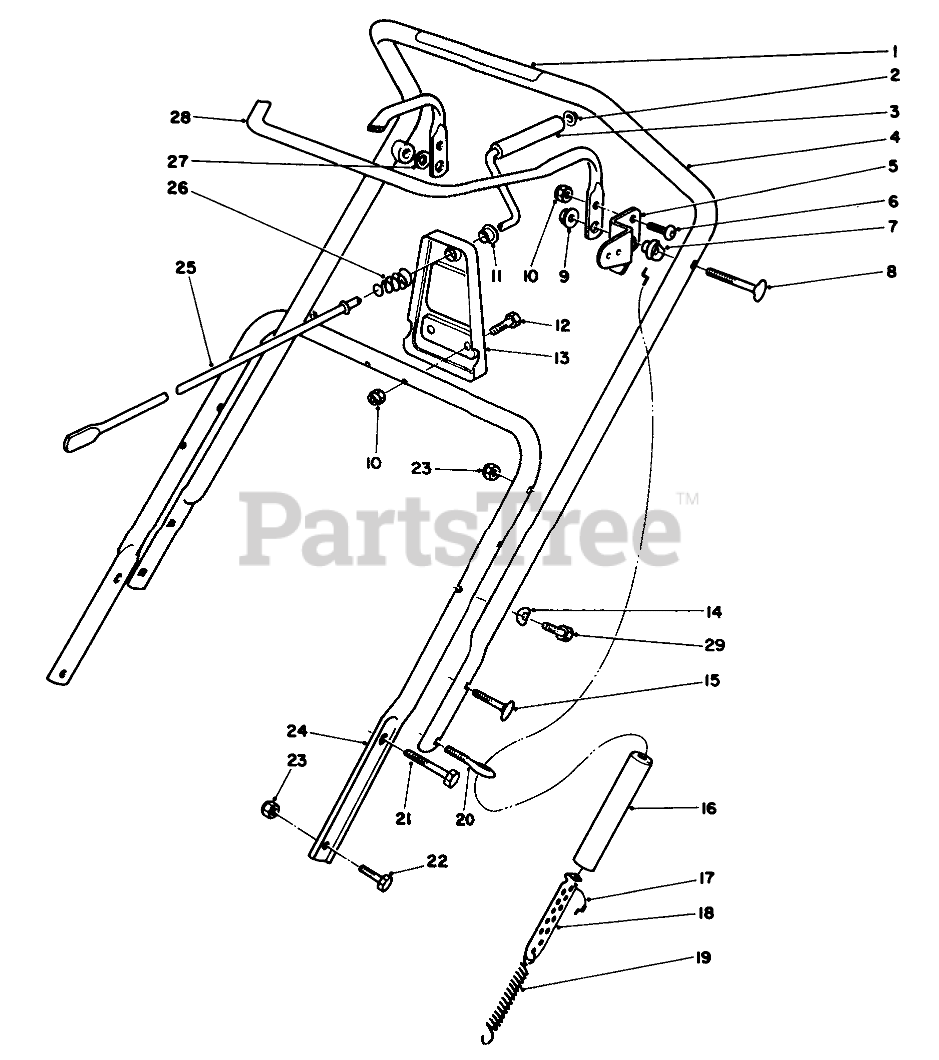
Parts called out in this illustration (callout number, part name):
1	Decal-Rotor Drive
1	ROTOR DRIVE DECAL
2	RETAINER-PUSH ON
3	GRIP-CONTROL, CHUTE
4	Upper Handle Assembly (Incl. Ref. #1)
5	Arm-Clutch Cable
6	SCREW-HSBH
7	SPACER-BAR, CONTROL
8	SCREW-HANDLE
9	NUT-LOCK, NI
10	NUT-LOCK, NI
11	Bushing
12	SCREW-HH
13	Support-Crank
14	WASHER
15	SCREW
16	COVER-SPRING
17	CABLE-CLUTCH
18	ADJUSTER-CABLE
19	SPRING-EXTENSION
20	BOLT-EYE
21	SCREW-HH
22	SCREW-HH
23	NUT-LOCK, NI
24	LOWER HANDLE
25	ROD-CRANK, CHUTE
26	SPRING-COMPRESSION
27	WASHER
28	Bar-Control
29	SCREW
